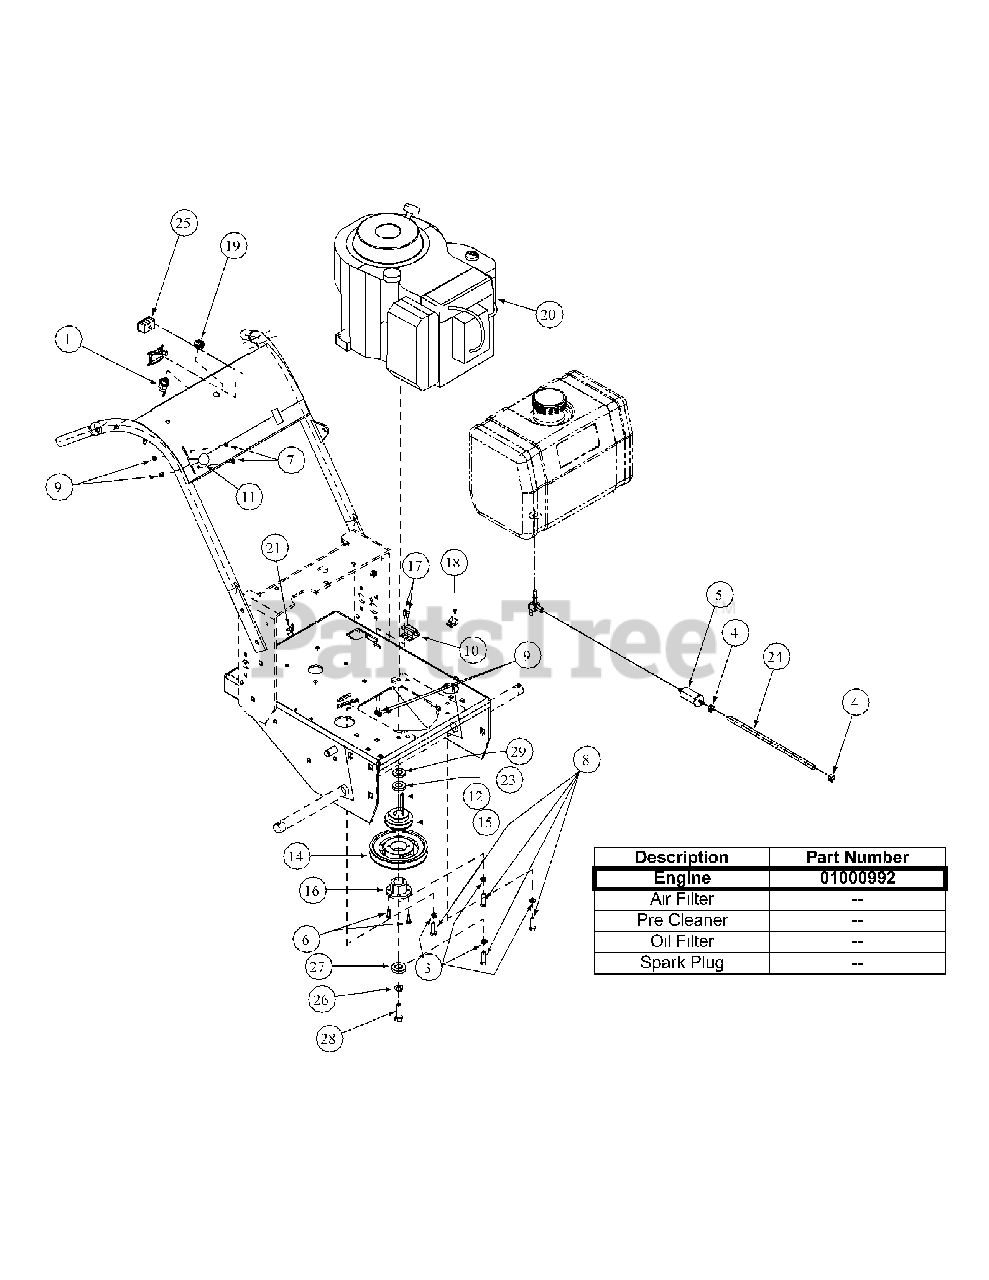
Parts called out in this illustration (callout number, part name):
1	Single Ignition ON/OFF Switch
2	Harness Hour Meter
3	Lock Washer, 5/16
4	Clamp
5	Kohler Fuel Filter
6	Harness Adapter,
7	Screw, Hex Washer, 10-32 x 1/2
8	Cap Screw, 1.25 x 30
9	Lock Nut, Nylon Insert, 10-32
10	Delta Switch
11	Control Throttle w/Detent, 39.2
12	Key Stick, 1/4 x 1/4 x 2-1/4
13	Harness Wire
14	Deck Pulley
15	Traction Pulley
16	Bushing
17	Machine Screw, 10-32 x 5/8
18	Support Clamp Tubing, 1/2"
19	Nut w/cap, 5/8-32 Ignition
20	13HP Kohler Engine
21	Support Clamp, 3/8 OD
22	Belt
23	Flat Washer
25	Hour Meter
26	Lock Washer, 7/16
27	Clutch Washer
28	Hex Cap Screw, 7/16-20 x 1.25 Lg
29	Spacer, Engine Pulley
